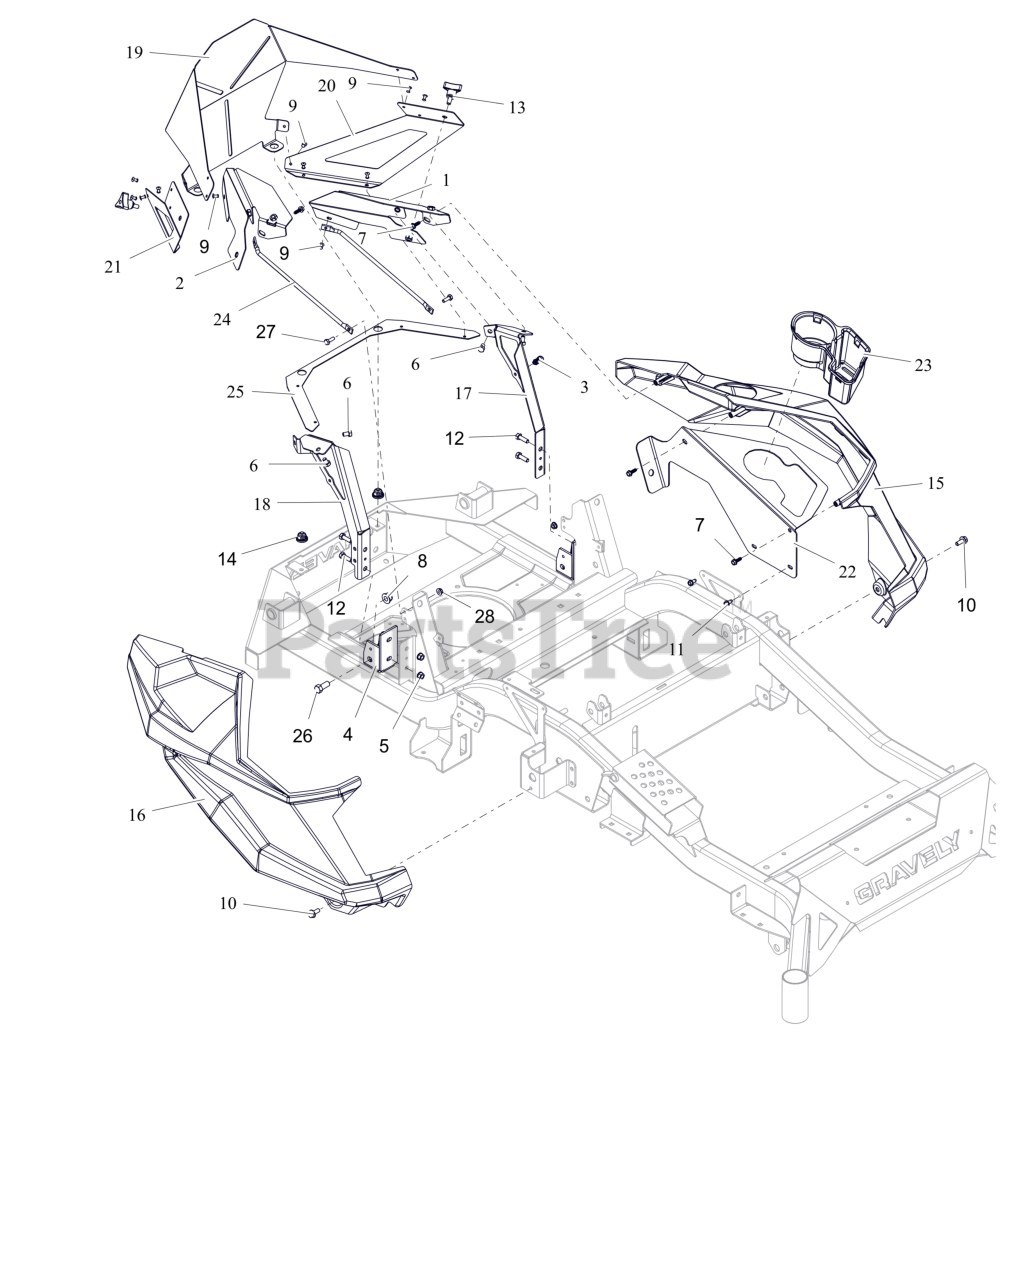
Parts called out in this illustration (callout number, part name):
1	PANEL, LH (RED)
2	PANEL, RH (RED)
3	CLIP, CABLE GUIDE
4	BRKT, ROPS SUPPORT
5	NUT,LK-CTR-FLG .31-18 GF ZCC
6	BLT, HEX .31-18X.50 GR5 ZCC
7	SCR, PLASTITE-HWH 0.25 X 0.75 ZC120
8	NUT,NYL-FLG .44-14 GF ZCC
9	RIVET, #66 STEEL POP PD BLACK
10	BLT, SERHFWH 0.312-18X0.75 GR5 ZCC
11	SCR-TAP .25-20X.50 HWH ZCC
12	BLT, HEX .31-18X1.00 G8 ZCC
13	KNOB,WING STUD 5/16-18 X .75
14	GROMMET, 10MM BOLLHOFF
15	FENDER, LH
16	FENDER, RH
17	BRKT, LH FENDER MTG (RED)
18	BRKT, RH FENDER MTG (RED)
19	WRAP, REAR (BLACK)
20	WRAP, REAR - LH (RED)
21	WRAP, REAR - RH (RED)
22	PANEL, HD CUPHOLDER (RED)
23	HOLDER, CUP
24	ROD, STIFFENER
25	STIFFENER, BACK WRAP (RED)
26	BLT, HEX 0.4375-14X1 GR5 ZCC
27	BLT, HEX .25-20X.75 G5 ZCC
28	NUT-LK-CTR-FLG .25-20 ZC120
